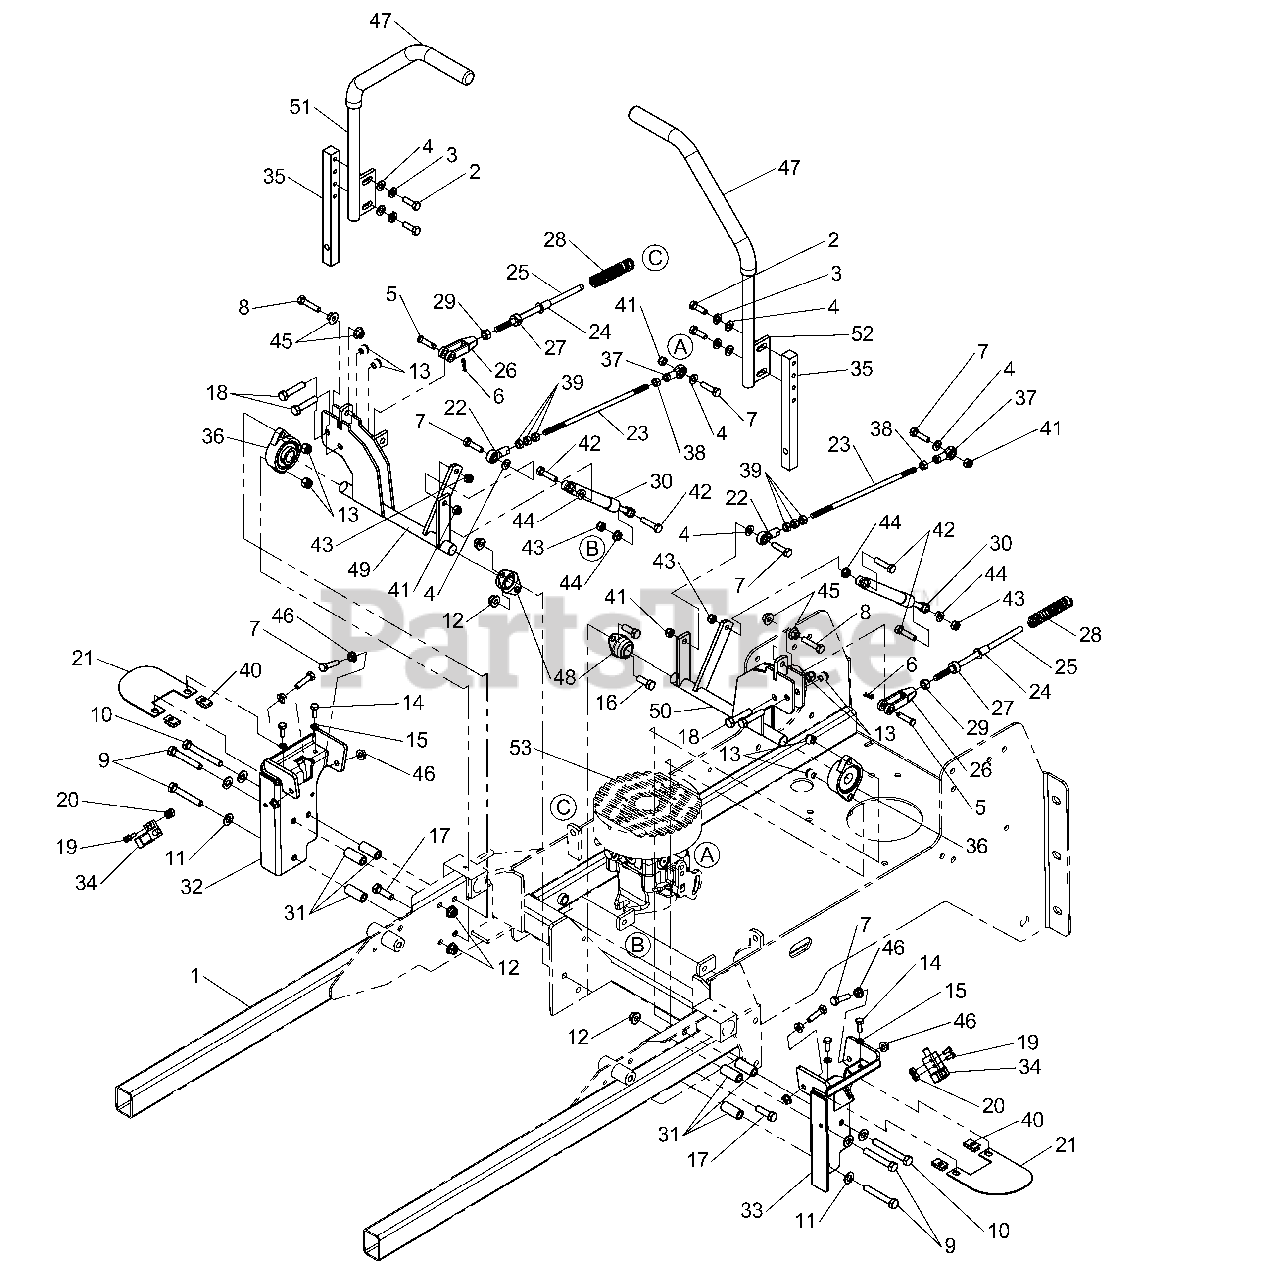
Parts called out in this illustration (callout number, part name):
1	MAIN FRAME (See Main Frame Group)
2	BOLT, 5/16-18 X 1"
3	WASHER, 5/16" Lock
4	WASHER, 5/16" SAE
5	CLEVIS PIN, 5/16" X 1-1/4"
7	BOLT, 5/16-18 X 1-1/4"
8	BOLT, 5/16-18 X 1-1/2"
9	BOLT, 3/8-16 X 2-1/2"
10	BOLT, 3/8-16 X 3"
11	WASHER, 3/8" SAE
12	NUT, 3/8-16 Hex Nylock Flange
13	NUT, 3/8-16 Hex Nylon Lock
14	BOLT, 1/4-20 X 3/4"
15	WASHER, 1/4 SAE (5025154)
16	BOLT, 3/8-16 X 1"
17	BOLT, 3/8-16 X 1-1/4"
18	BOLT, 3/8-16 X 1-3/4"
19	SCREW, #10-24 X 1/2"
20	NUT, #10-24 Hex
21	MOTION CONTROL GUARD
22	BALL JOINT 5/16-24 RH FEMALE STAMPED STL
23	HYDRO CONTROL ROD
24	BUSHING, Flange
25	NEUTRAL CONTROL ROD
26	CLEVIS, 3/8-24, Plastic
27	COLLAR, 3/8" Set
28	SPRING, Compression
29	NUT, 3/8-24 Hex
30	DAMPENER
31	SPACER, .63 X .39 X 1.50
32	NEUTRAL LOCK PLATE, RH
33	NEUTRAL LOCK PLATE, LH
34	SWITCH, PLUNGER, N.O./N.C.
35	MOUNT, CONTROL ARM - BLK
36	BEARING, Flange
37	BALL JOINT 5/16-24 LH FEMALE STAMPED STL
38	NUT, 5/16-24 Hex LH
39	NUT, 5/16-24 Hex
40	BODY CLIP, 1/4-20
41	NUT, 5/16-18 Hex Nylon Lock
42	BOLT, M8-1.25 x 35MM
43	NUT, M8-1.25 Hex Nylon Lock
44	NUT, M8-1.25 Hex Serrated Flange
45	NUT, 5/16-18 Hex Large Serrated Flange
46	NUT, 5/16-18 Hex Small Serrated Flange
48	BEARING, Flange
49	CONTROL SHAFT, RH
50	WCONTROL SHAFT, LH
51	WELD, HANDLE MOTION CONTROL, RH - BLK
52	WELD, HANDLE MOTION CONTROL, LH - BLK
53	HYDRAULIC PUMP (See Hydraulic Group)
